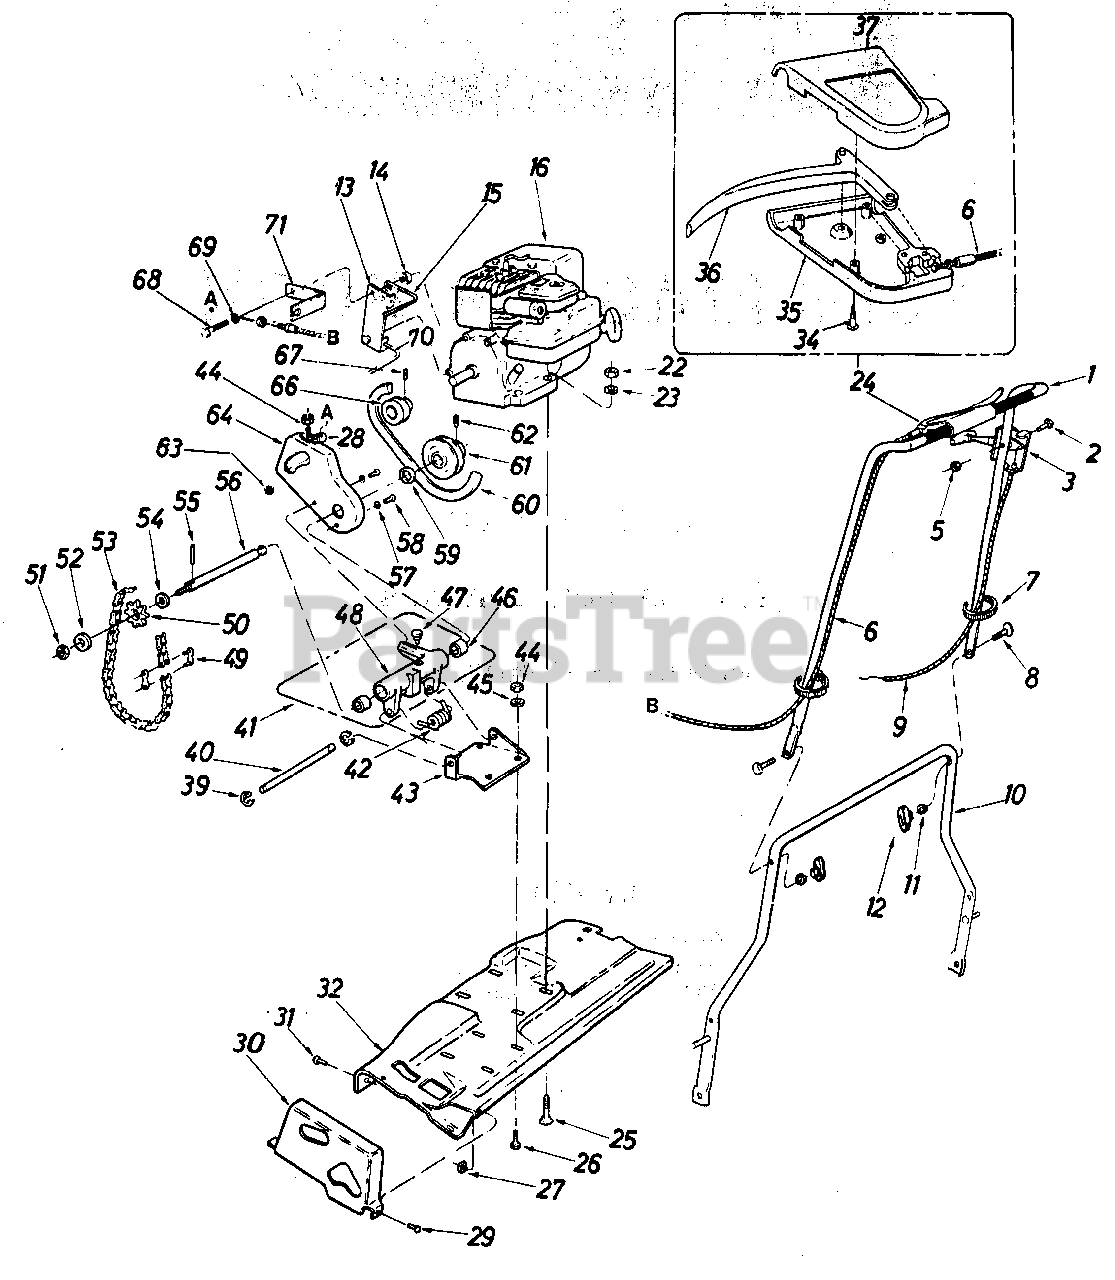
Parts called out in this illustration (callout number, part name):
1	Upper Handle Ass'y.
2	Rd. Hd. Scr. 1/4-20 x 1.88" Lg.
3	Throttle Control Ass'y.
5	Capped Wash. Z-Nut
6	Clutch Control Cable
7	Cable Tie
8	Special Scr. 5/16-18 x 1.75" Lg .
9	Throttle Cable
10	Lower Handle Ass'y.
11	L-Wash. 5/16
12	Handle Knob
13	Belt Keeper Brkt.
14	Spacer
15	Belt Keeper Upper
22	Hex Nut 5/6-18 Thd.
23	L-Wash. 5/16
24	Clutch Control Ass'y.
25	Carriage Bolt 5/16-18 x 1.375" Lg.
26	Scr. "4-20 x .625" Lg.
27	Hex L-Nut 10-32 Thd.
28	Clevis Lanyard Fitting
29	Ph. Hd. Scr. 10-32 x .375" Lg.
30	497 Chain Guard
31	Hex Sems Scr. 5/16-24 x .50 Lg.
32	18" Deck
34	Slotted Oval Self-Tap Scr. #10 x .87" Lg.
35	Rear Control Cover
36	Lever Clutch Control
37	Front Cover Control
39	Retaining Ring
40	1 Pin
41	Jack Shaft Hsg. and Brg. Ass'y.
42	Spring
43	Bracket
44	Hex Nut1/4-20 Thd.
45	1/4 Split L-Wash.
46	Bearing
47	Oiler
48	IJack Shaft Hsg.
49	Connector Link
50	Sprocket
51	IHex Jam Nut 5/16-24
52	Washer
53	: Chain
54	IWash. 5/8 x 15/16
55	j Pin
56	Jack Shaft
57	Washer
58	Ph. Hd. Scr. 10-32 x .50' Lg.
59	Wash. 518 x 15/16
60	"V" Belt
61	Pulley Ass'y.
62	Roll Pin
63	Hex Nut 1/4-20 Thd.
64	497 Belt Guard Ass'y.
66	Pulley
67	Set Scr. 5/16-24 x 7/32" Lg.
68	Ph. Hd. Scr. 1/4-20 x 1.75" Lg.
69	L-Wash. 1/4" Scr.
70	Belt Keeper Lower
71	Clutch Cable Bracket
